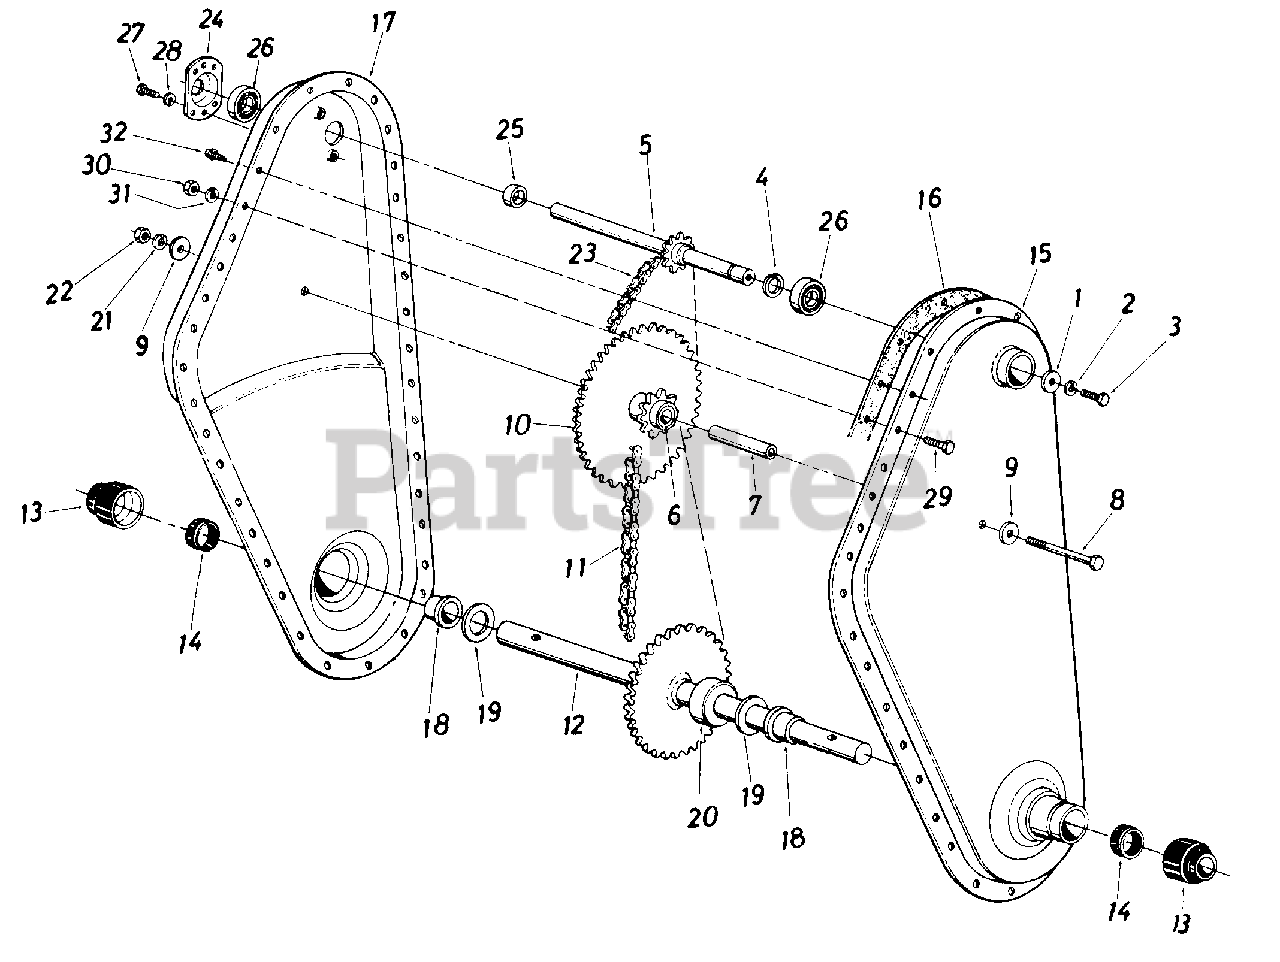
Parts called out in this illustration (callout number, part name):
1	WASHER-FL
2	LOCK WASHER 1/4 DIA
3	BOLT - 1/4-28 X 5/8 61.5
4	RING-SNAP
5	SHAFT-INPUT
7	HUB-SPROCKET
8	SCREW-HEX 3/8-16 X 2.75
9	WASHER-FL-.385 X 1.00 X .135
10	SPROCKET ASSY-8T & 40T
11	#50 CHAIN 5/8 PITCH X 46 LINKS E
12	SHAFT ASSY-TINE
13	CAP-DUST
19	WASHER-FL-1.03 ID X 1.62 X .03 HD
20	SPACER
21	WASHER-LOCK-3/8
22	NUT-HEX JAM 3/8X24
23	#35 CHAIN 3/8 PITCH X 52 LINKS E
24	HOUSING-BRG
26	BEARING-BALL
27	SCREW-HEX WASH SF TAPP
28	LOCK WASHER 1/4 DIA
29	SCREW-HEX 5/16-18 X .75
30	NUT-HEX 5/16-18
31	WASHER-LOCK-5/16
32	SCREW-HEX WASH SF TAPP
